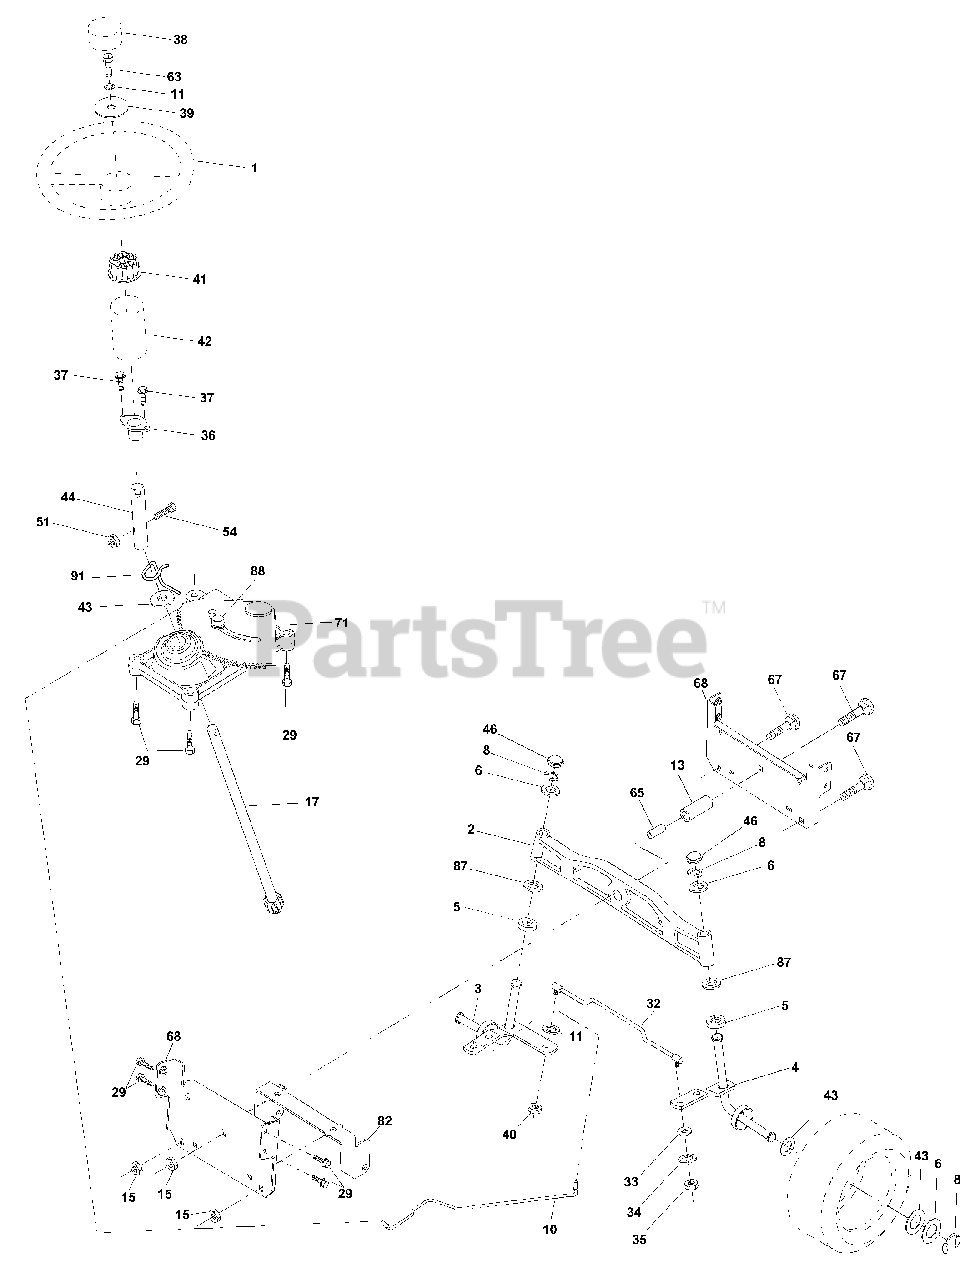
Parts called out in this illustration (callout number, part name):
1	Wheel Steering
2	Axle Asm Cast Iron LT
3	Spindle Asm LH
4	Spindle Asm RH
5	Bearing Race Thrust Harden
6	Washer 25/32 X 1-5/8 X 16 Ga
8	Ring Klip #t5304-75
10	Link Drag
11	Washer Lock Hvy Hlcl Spr 3/8
13	Spacer Brg Axle Front
15	Nut Hex Flange Lock
17	Shaft Asm Strg
29	Screw 3/8-16 x .75
32	Rod Tie
33	Washer 11/32 x 3/4 x 16 Ga
34	Washer Lock Hvy Hlcl Spr 5/16
35	Crownlock Nut 5/16-24 Unf
36	Bushing Strg
37	Screw
38	Insert Cap Strg Wh
39	Washer 13/32 X 1-1/2 X 11 Ga
40	Lock nut
41	Adaptor Wheel Strg
42	Boot Steering Dash
43	Washer 25/32 X 1 1/4 X 16 Ga
44	Extension Steering Shaft LR/LT
46	Cap Spindle Fr Top Blk
51	Nut Lock Hex w/Ins 5/16-18
54	Bolt Fin Hex 5/16-18 Unc x 1-1/4
63	Bolt Fin Hex 3/8-16unc x 1 Gr. 5
65	Spacer Brace Axle
67	Bolt Rdhd Sq 3/8-16 Unc x 2-3/4
68	Axle, Brace
71	Steering Asm
82	Bracket Susp Chassis Front
87	Washer Flat .781 x 1-1/2 x .14
88	Bolt Shoulder 7/16-20
91	Clip Steering
